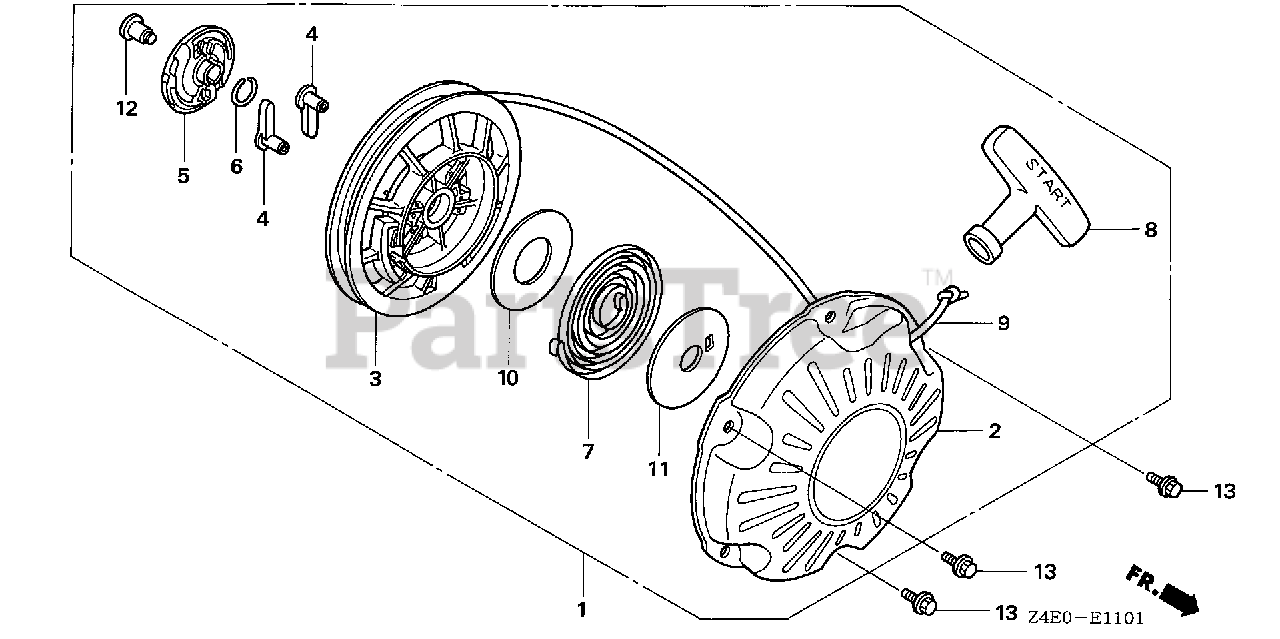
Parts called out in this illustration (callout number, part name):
1	STARTER ASSY., RECOIL *NH1* (BLACK)
1	STARTER ASSY., RECOIL *R280* (POWER RED)
2	CASE, RECOIL STARTER *NH1* (BLACK)
2	CASE, RECOIL STARTER *R280* (POWER RED)
3	REEL, RECOIL STARTER
4	RATCHET, STARTER
5	GUIDE, RATCHET
6	SPRING, FRICTION
7	SPRING, RECOIL STARTER
8	GRIP, STARTER
8	KNOB, RECOIL SRARTER
9	ROPE, RECOIL STARTER
10	PLATE, SIDE
11	PLATE, SLIDE
12	SCREW, SETTING
13	BOLT, FLANGE (6X8)
